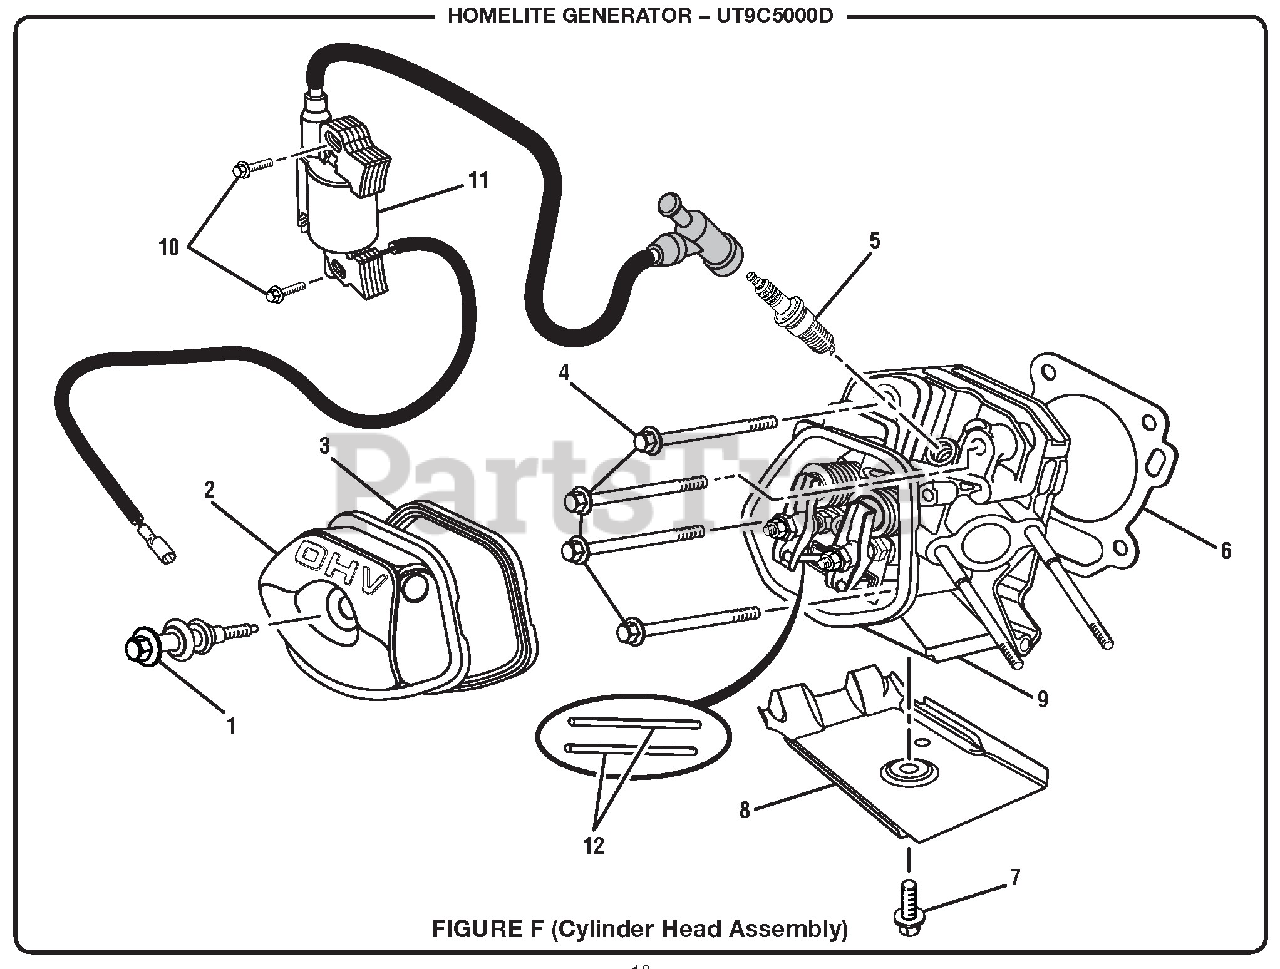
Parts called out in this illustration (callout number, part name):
1	Bolt Assembly (Valve Cover)
2	Valve Cover
3	Valve Cover Gasket
4	Bolt (M10 x 80 mm, Cylinder Head)
5	Spark Plug (Champion F7TC)
6	Cylinder Head Gasket
7	Bolt (M6 x 12 mm, Flange Hd)
8	Lower Cover (Cylinder Head)
9	Cylinder Head Assembly
10	Bolt (M6 x 30)
11	Ignition Coil Assembly
